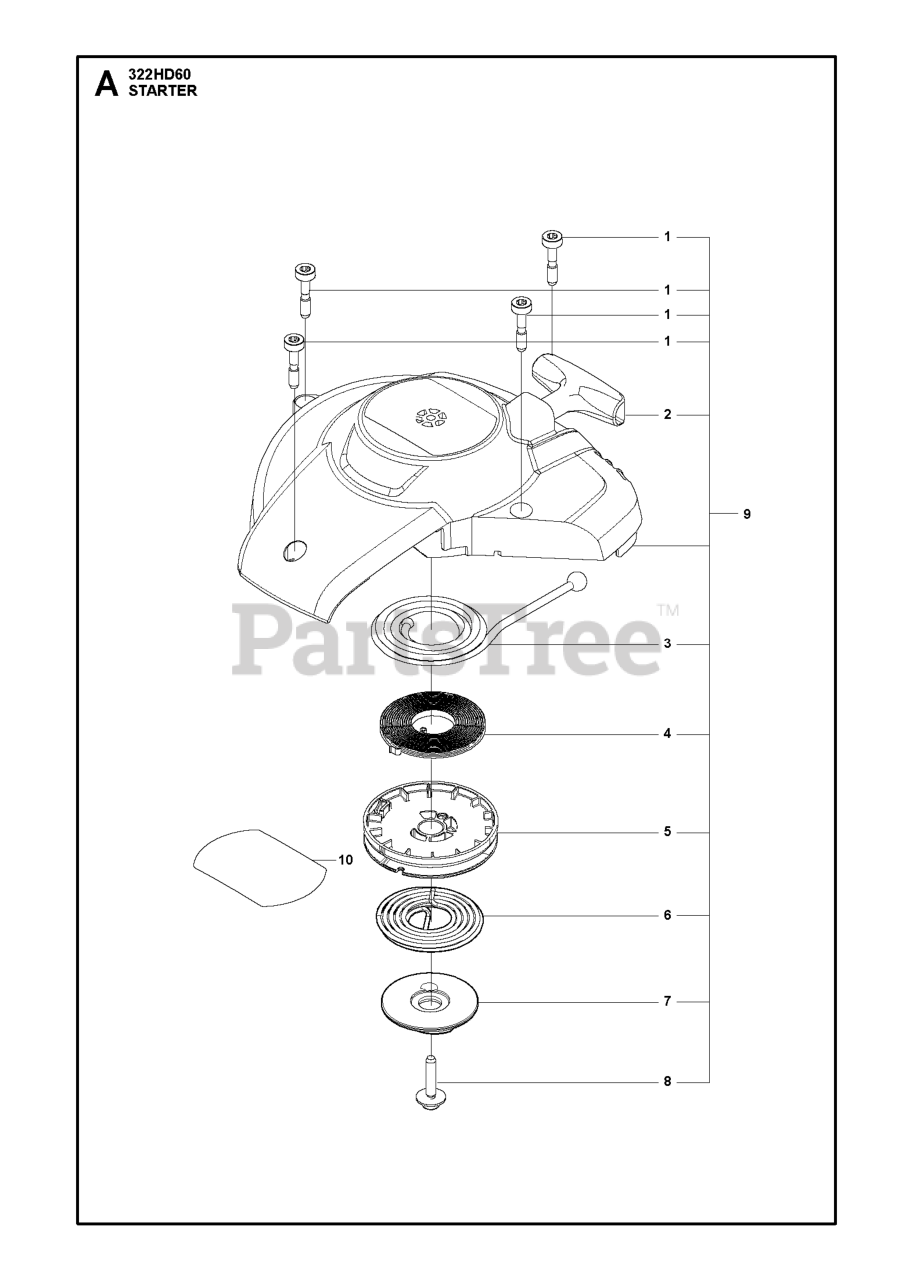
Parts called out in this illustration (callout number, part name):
1	SCREW CITXSCMO M5X25
2	STARTER HANDLE
3	STARTER CORD
5	STARTER PULLEY
